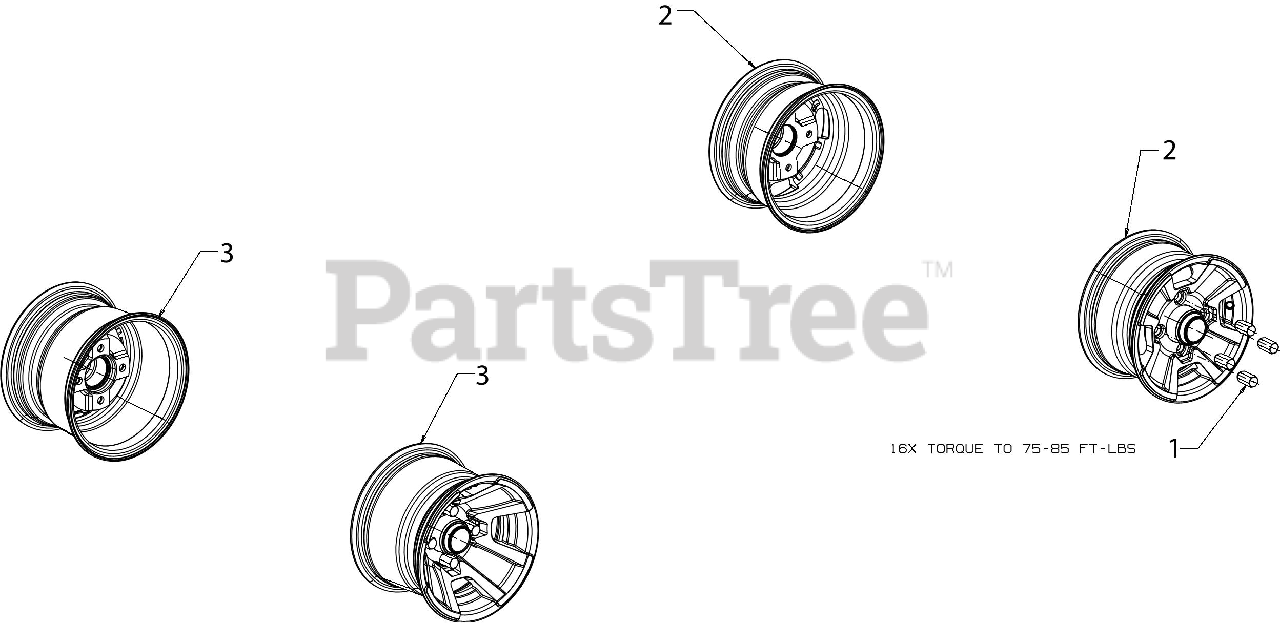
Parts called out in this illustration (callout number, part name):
1	LUG NUT 1/2-20 CHROME
2	RIM 10 X 5.5
3	RIM 10 X 7
